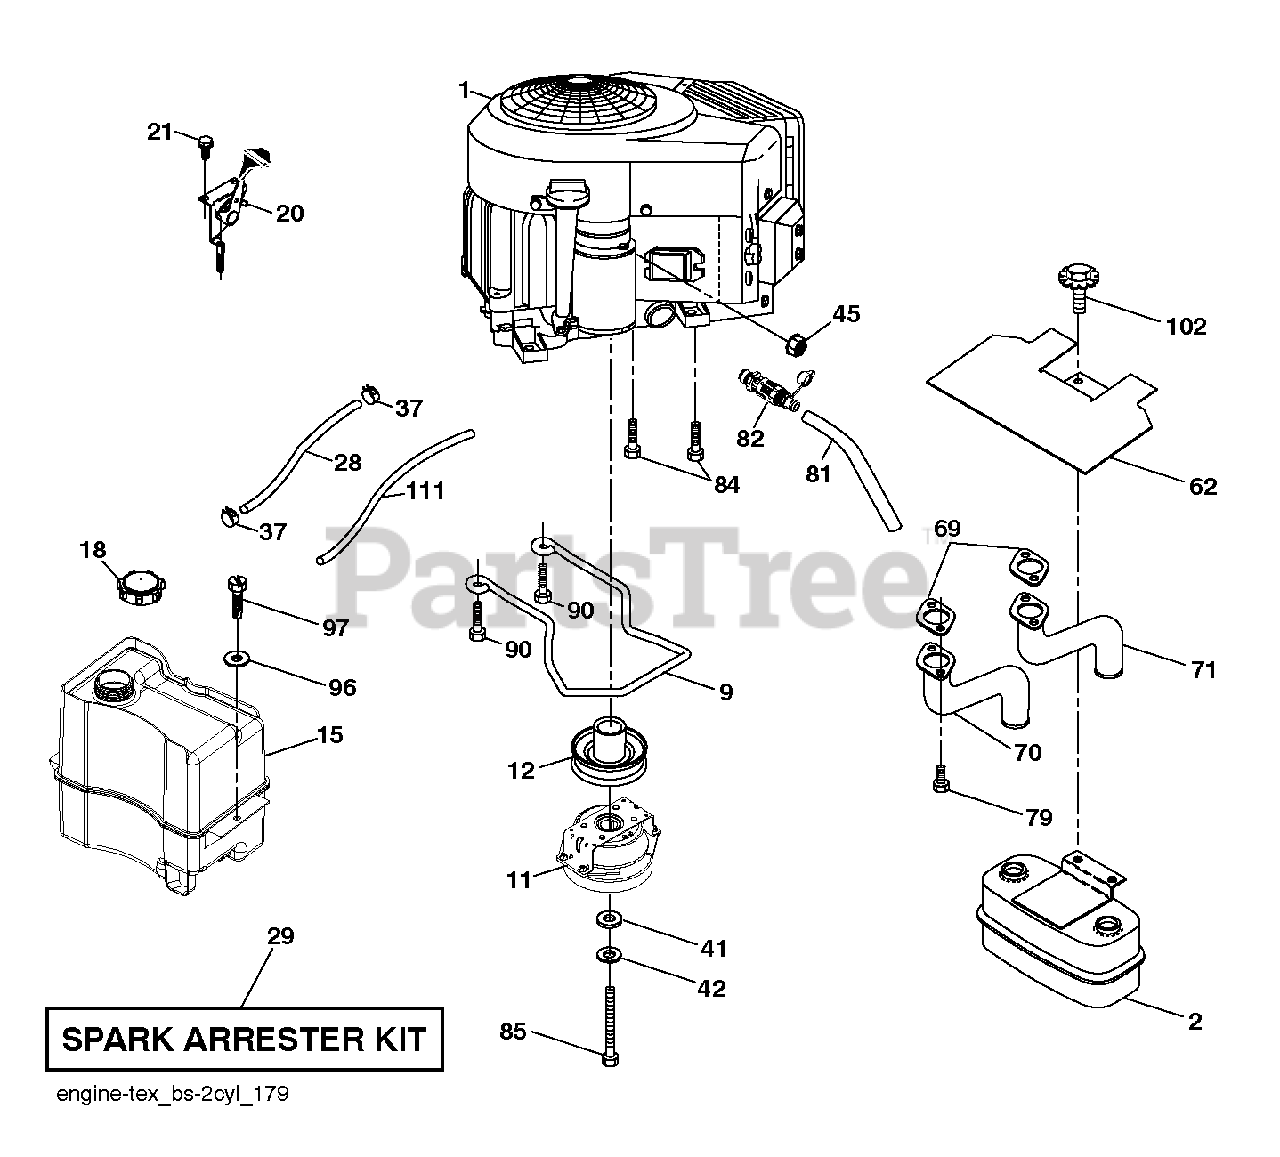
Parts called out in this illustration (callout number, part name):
2	Muffler Assembly, Twin MN
9	KEEPER.BELT.ENG.4.25"2.BLT.431
11	CLUTCH.OGURA.5.0PD.GT1.5A-EH07
12	PULLEY.ENGINE.TUFFTORQ
15	Front Tank Assembly, 2.5 Gallon
18	FUEL.CAP.ASM.2.25TETHRED.RATCH
20	THROTTLE.COBRA.38"READSTART.BK
21	SCREW.#10 X 0.750.BOS
28	LINE.FUEL.64"REAR.EMIS
29	KIT.SPARK ARRESTOR 794945 B&S
37	HOSE CLAMP
42	WASHER 7/16 LOCK
45	NUT
62	SHIELD.HEAT.MUFFLER
69	GASKET.MUFFLER
70	EXHAUST.TUBE.LH.BS/TWIN
71	EXHAUST.TUBE.RH.B&S.TWIN.INTEK
79	SCREW.SOCKET.HEAD.5/16-18
81	TUBE, DRAIN OIL ASM.
82	VALUE.OIL.DRAIN
84	SCREW.3/8-16
85	BOLT.HEX.7/16-20X3.75.GR5.RED
90	SCREW 3/8-16X1
102	SCREW
111	RP PURGE LINE
